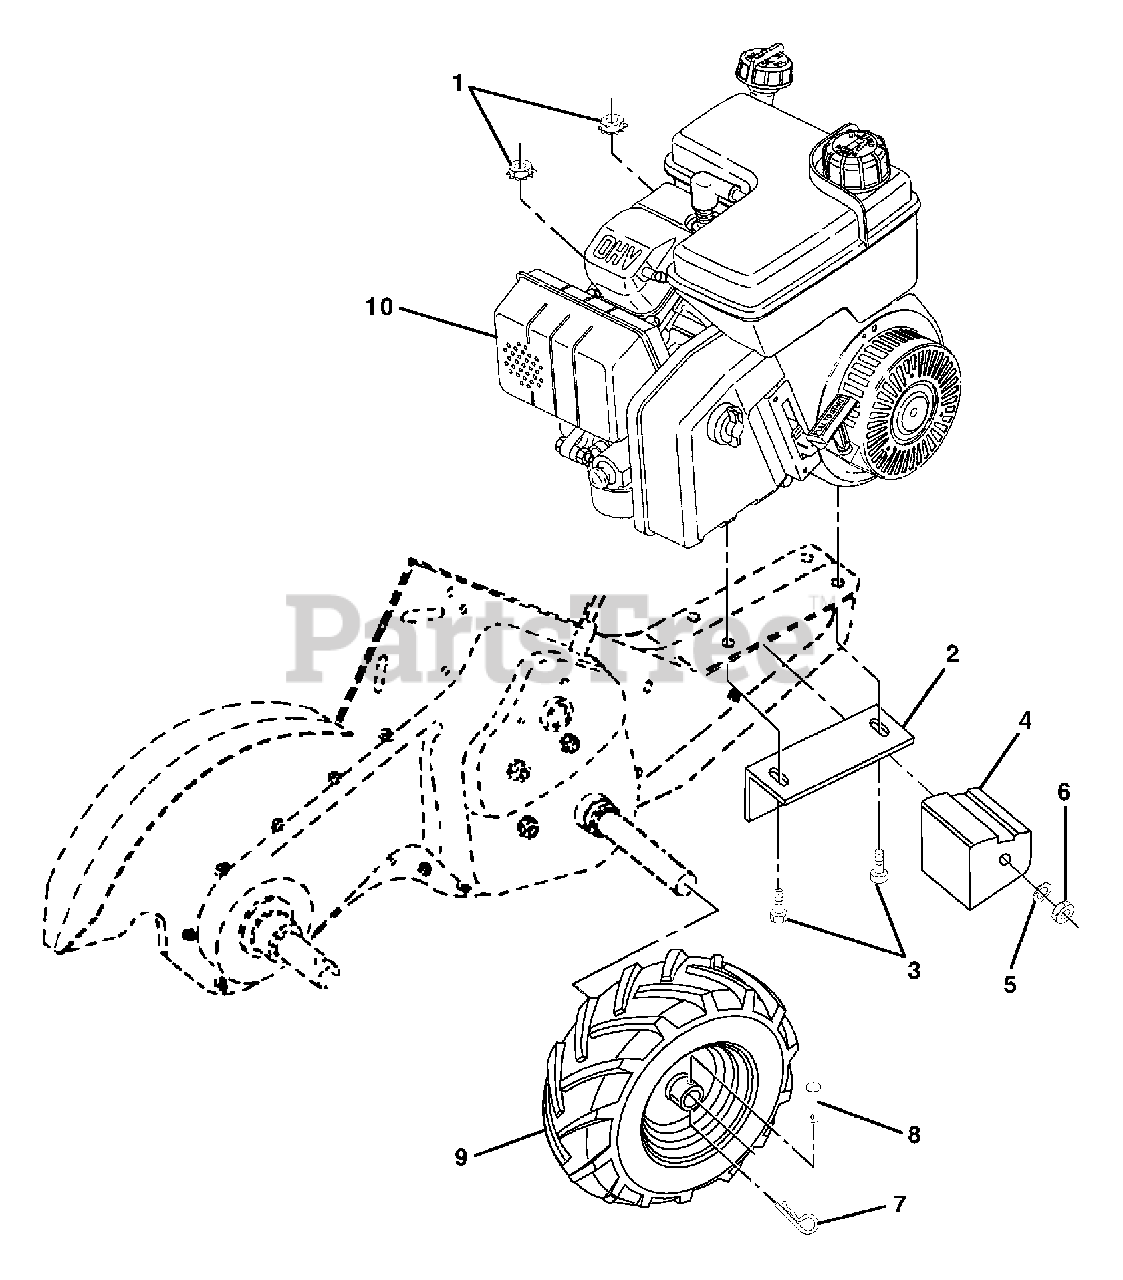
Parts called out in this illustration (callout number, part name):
1	Nut, Keps 5/16-18
2	Bracket, Reinforcement
3	Bolt, Hex 5/16-18 x 1-1/2
4	Counter Weight, R.H.
5	Washer, Lock 3/8
6	Nut, Hex 3/8-16
7	Clip, Hairpin
8	Rivet, Drilled
9	Rim
9	Tire Valve
10	Engine
